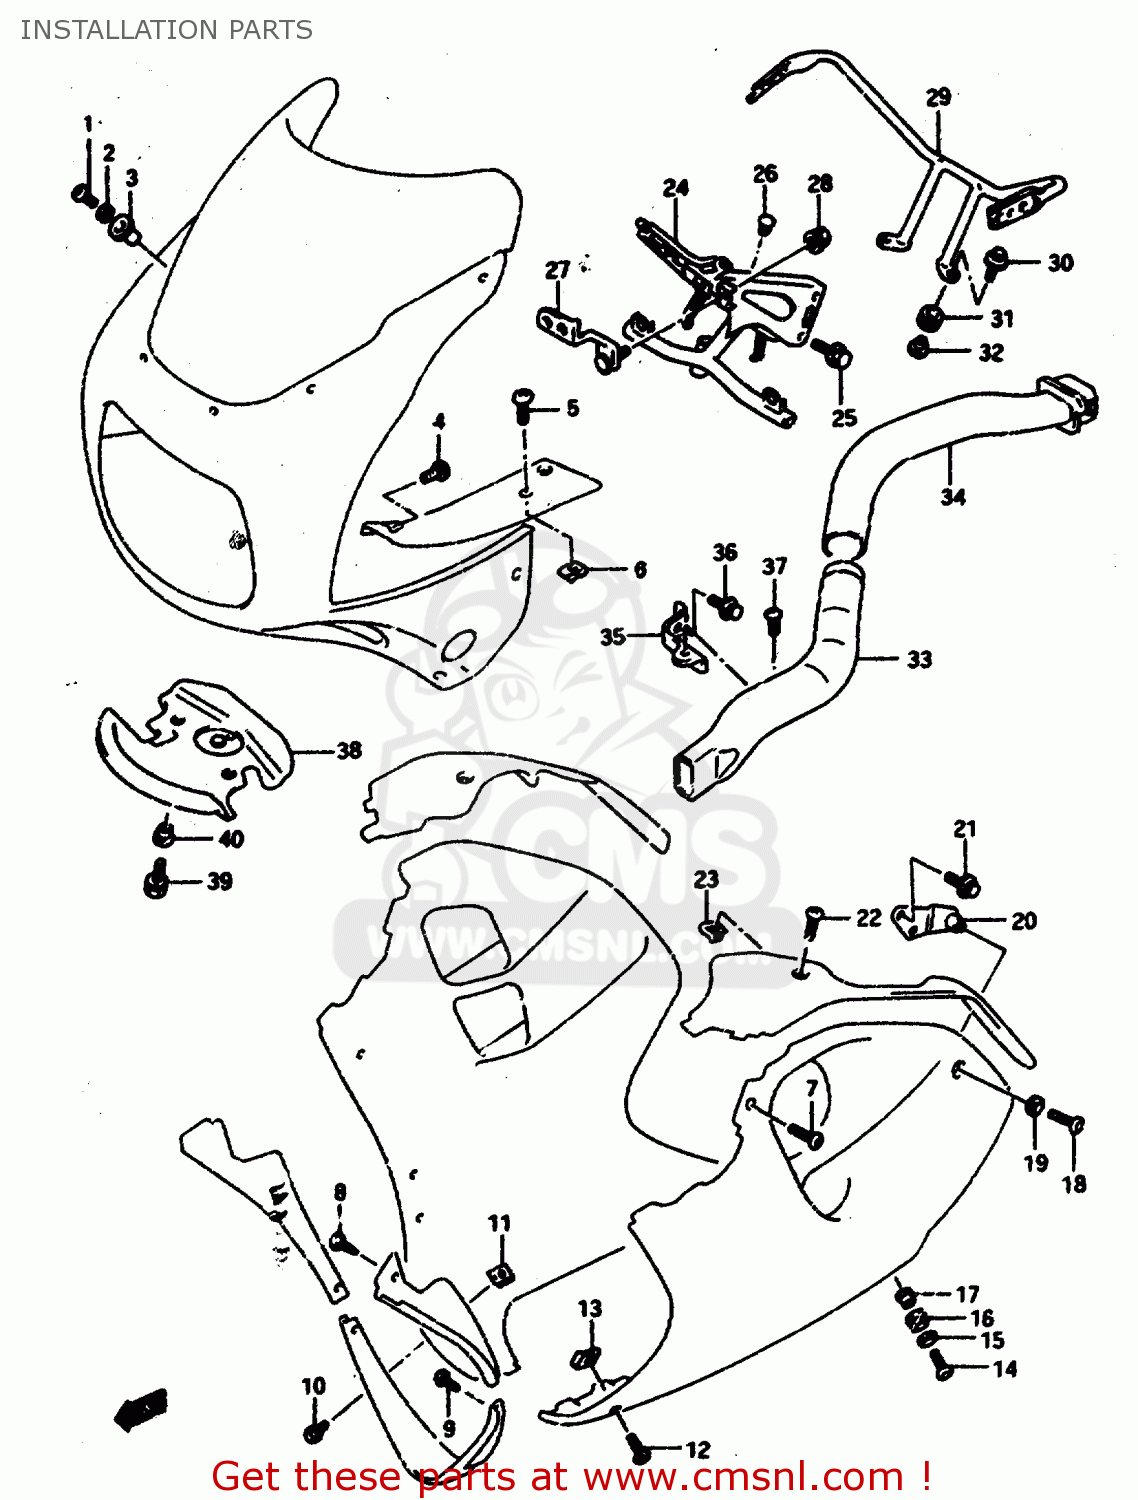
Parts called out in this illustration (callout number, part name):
1	SCREW(5X14)
2	WASHER
3	NUT
4	SCREW 5X10
5	SCREW L:12
6	NUT
7	SCREW(5X16)
8	SCREW 5X10
9	SCREW 5X10
10	SCREW(5X16)
11	NUT,HEADLAMP HOUSING,UPPER
12	SCREW(5X16)
13	NUT,HEADLAMP HOUSING,UPPER
14	SCREW(6X25)
15	WASHER(6.5X18X1)
16	CUSHION
17	WASHER
18	SCREW(6X10)
19	WASHER
20	BRACKET,UNDER COWLING UPR,R
21	BOLT
22	SCREW L:12
23	NUT
24	BRACE,COWLING
25	BOLT
26	CAP(OD:14)
27	BRACKET,HEADLAMP
28	NUT
29	BRACE,RR VIEW MIRRORR
30	BOLT(6X25)
31	CUSHION
32	WASHER,MIRROR BRACE,IN
33	PIPE,AIR INTAKE FR,L
34	PIPE,AIR INTAKE RR
35	BRACKET,AIR INTAKE,LEFT
36	BOLT
37	SCREW 6X12
38	COVER,COWLING FR LWR
39	BOLT
40	WASHER
